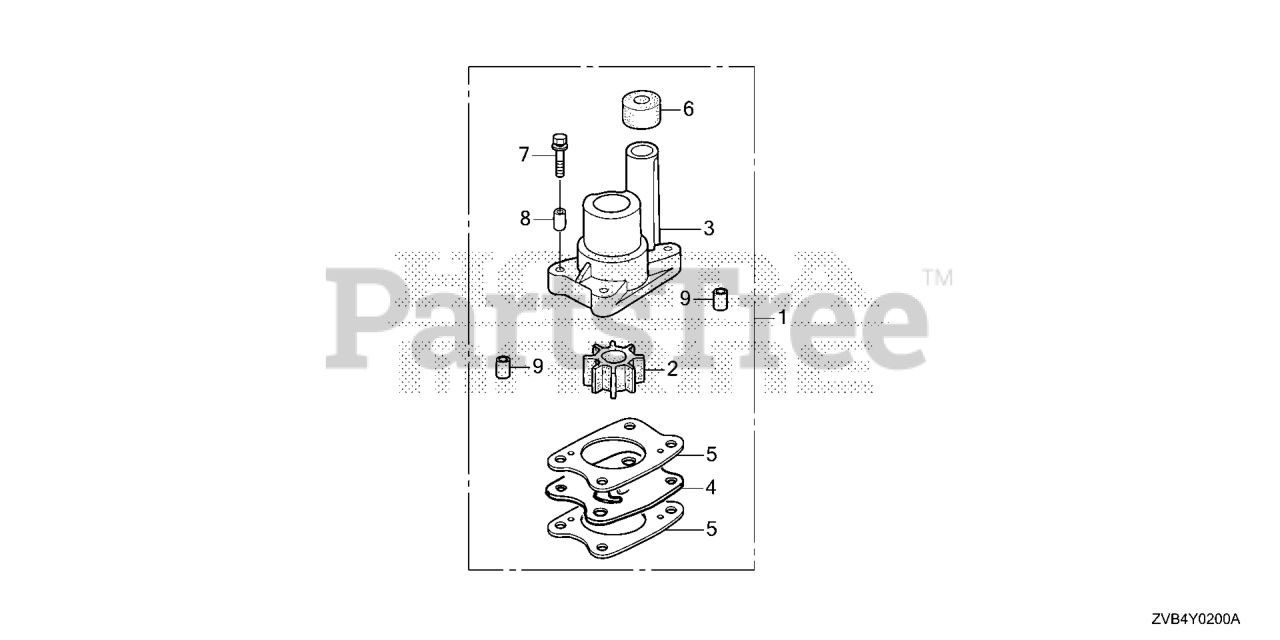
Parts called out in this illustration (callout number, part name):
1	PUMP KIT, IMPELLER
2	IMPELLER, PUMP
3	HOUSING, IMPELLER
4	COVER, IMPELLER
5	GASKET, IMPELLER
6	RING, WATER TUBE SEAL
7	BOLT-WASHER (6X29)
8	COLLAR B, DISTANCE
9	PIN A, DOWEL (8X14)
